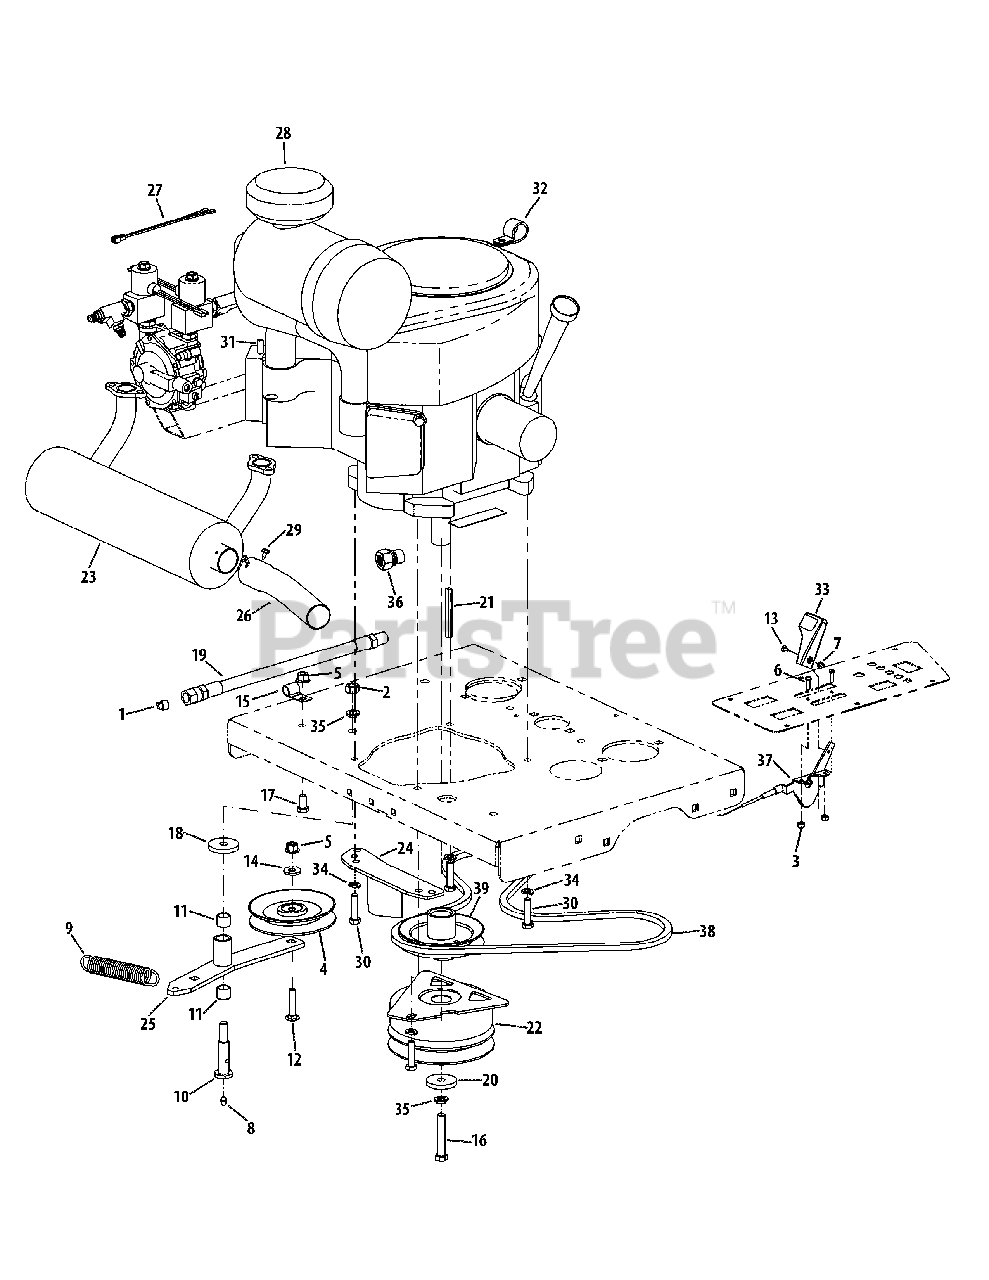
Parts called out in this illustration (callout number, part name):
1	Pipe Plug, 3/8
2	Nut, 7/16-14
3	Nut, #10-32
5	Flange Counterlock Nut, 3/8-16
6	Machine Screw, #10-32 x .625
7	Nut, #8-32
8	Grease Fitting, 1/4-28
9	Extension Spring, 1.00 x 5.00 x .125
10	Shoulder Bolt, .625 x 1.95
11	Sleeve Bearing, .628 x.753 x .625
12	Carriage Bolt, 3/8-18 x 1.75
13	Machine Screw, #8-32 x .356
14	Washer, .406 x 1.00 x .105
15	J-Clip, .470 x 1.80
16	Hex Screw, 7/16-20 x 2.50
17	Hex Screw, 3/8-16 x .750
18	Washer, .438 x 1.75 x .250
19	Oil Drain Hose
20	Washer, .438 x 1.745 x .250
21	Key, .250 x .250 x 3.00
22	Brake Clutch
24	Clutch Return Assembly
25	Engine Pulley Idler Arm Assembly
26	Exhaust Pipe
27	LPG Engine Harness Assembly
28	Kawasaki FX850V-AS000-S Engine
29	Hex Washer Screw, #10-16 x .500
30	Hex Screw, 3/8-16 x 1.50
31	Vinyl Cap, 1/4
32	Clamp, 1.0
33	Throttle Control Knob
34	Lock Washer, 3/8
35	Lock Washer, 7/16
37	Throttle Cable
39	Pump Drive Pulley
